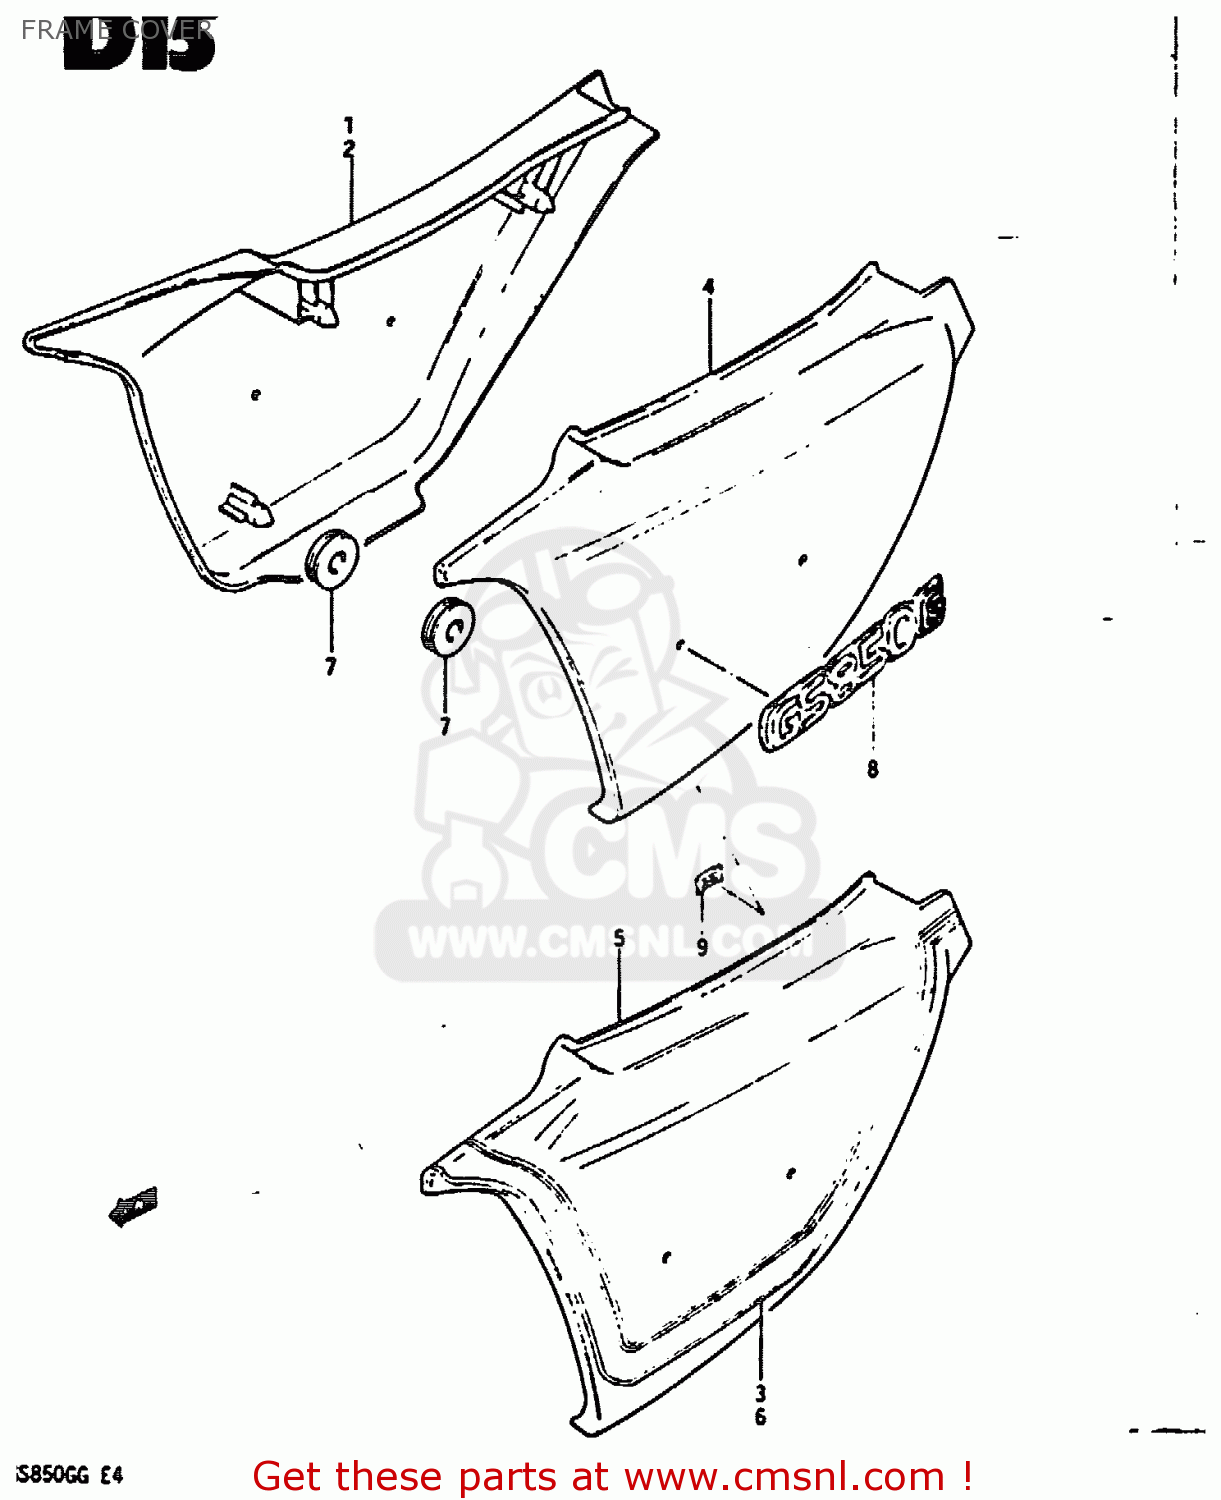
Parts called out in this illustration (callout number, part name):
1	COVER, FRAME RH (RED)
2	COVER, FRAME RH
3	TAPE SET, FRAME COVER RH
4	COVER, FRAME LH (RED)
5	COVER, FRAME LH
6	TAPE SET, FRAME COVER LH
7	CUSHION
8	EMBLEM,FRAME COVER
9	NUT
